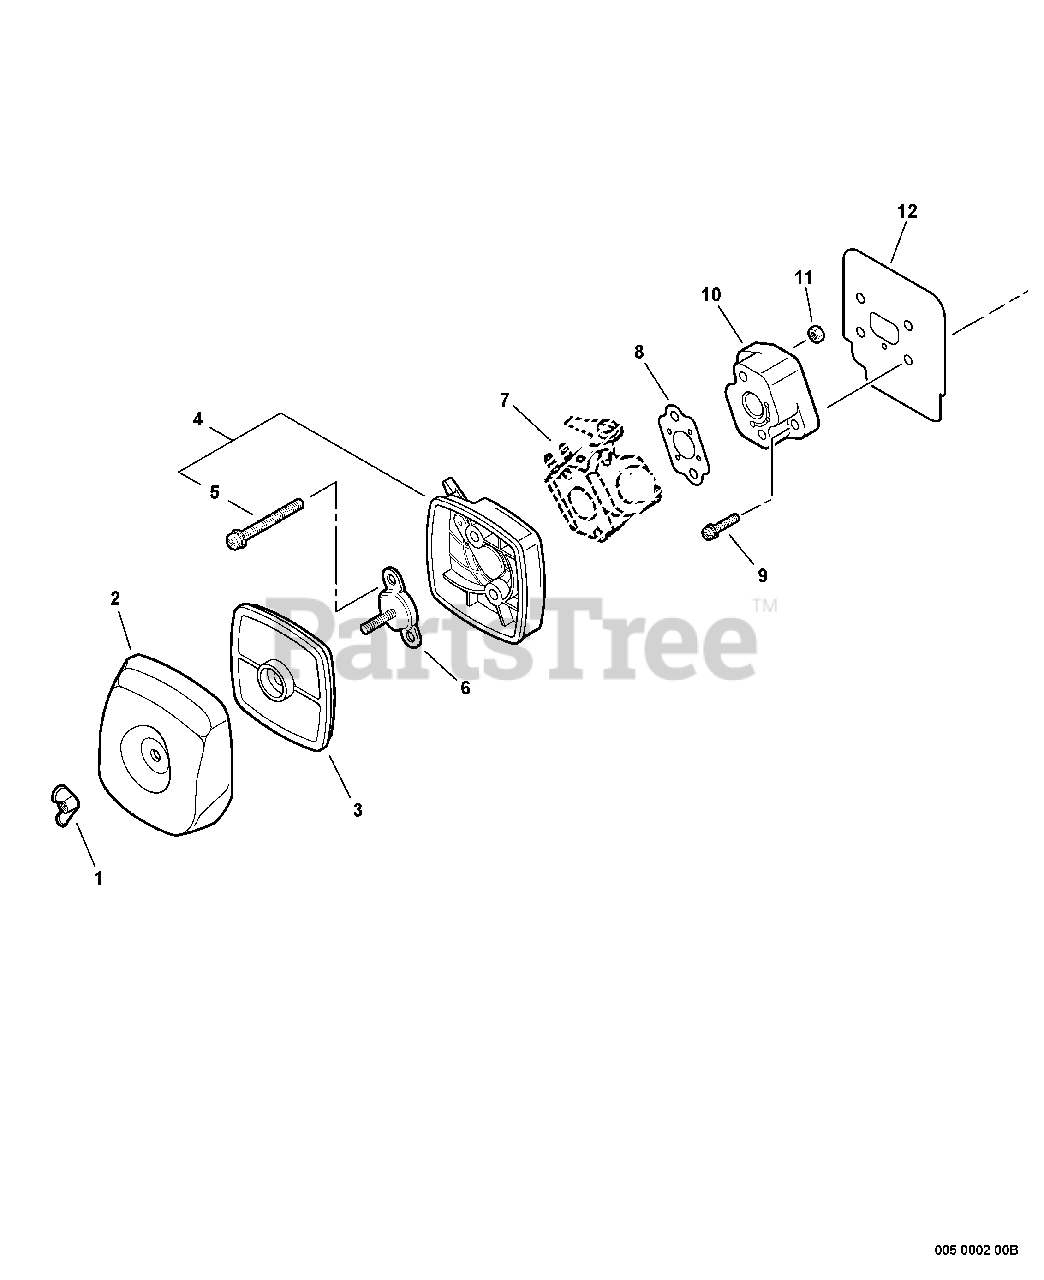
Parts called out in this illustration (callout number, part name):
1	WINGNUT - 6
2	COVER, AIR FILTER
3	FILTER, AIR - SINGLE LAYER
4	CASE, AIR FILTER - GRAY
5	SCREW 5×65
6	PLATE, PREVENT
7	CARBURETOR
8	GASKET, INTAKE
9	SCREW 5×20
10	INSULATOR, INTAKE
11	NUT M5
12	HEAT SHIELD, INTAKE
